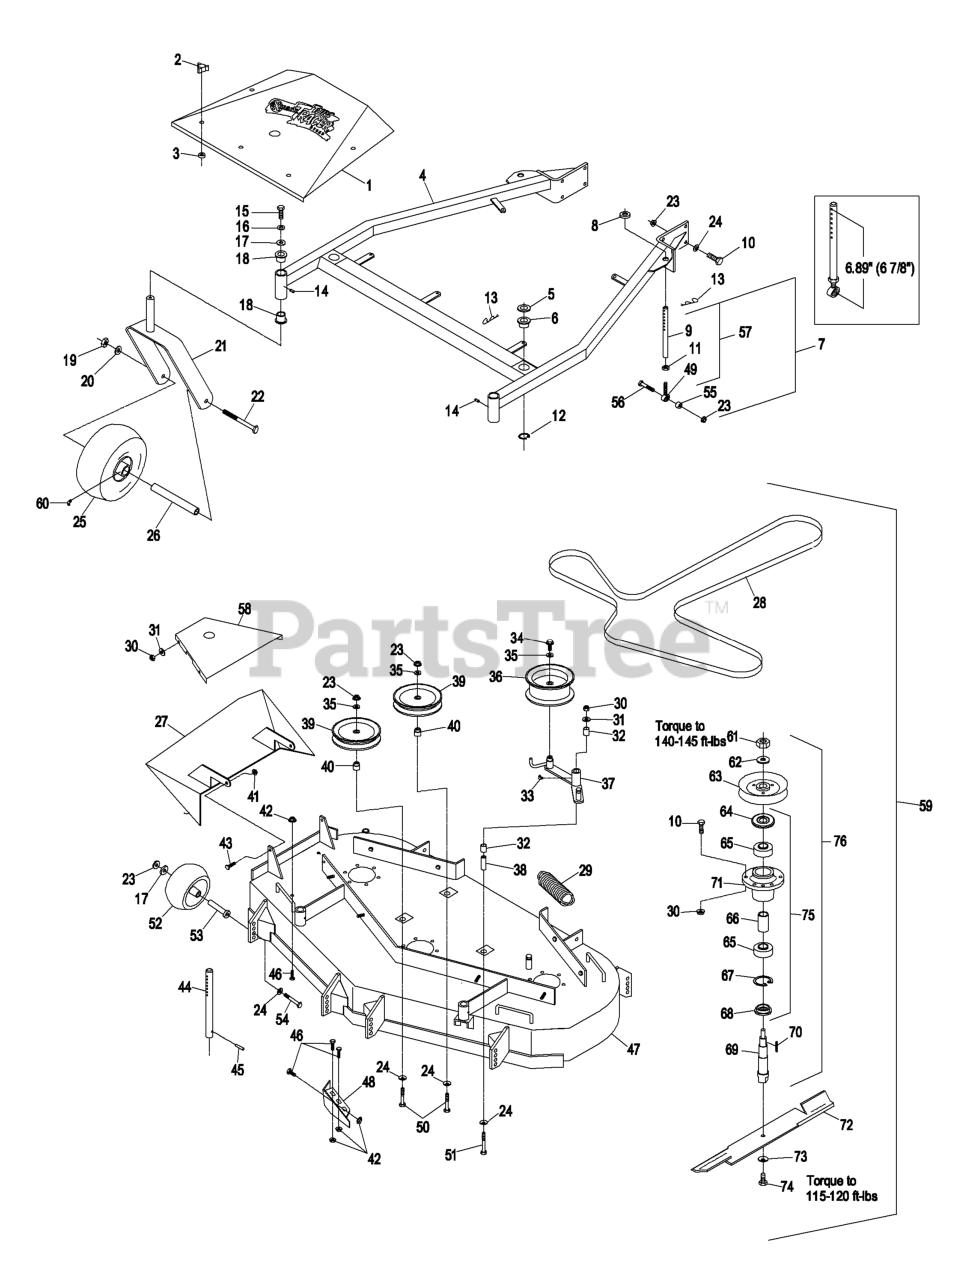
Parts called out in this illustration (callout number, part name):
2	KNOB-3 PRONG
4	SUPPORT,DECK W/BUSHINGS
5	SPACER-DECK SUPPORT
6	BUSHING-DECK
9	LINK,SUPPORT
10	SCREW-HH
11	NUT-HEX
12	RING-RETAINING
13	PIN,HAIR COTTER
14	FITTING-GREASE
15	SCREW-HH
16	WASHER-LOCK
18	BEARING-FLANGED
19	NUT-HH
20	WASHER-LOCK
22	SCREW-HH
23	NUT-HHF, WHIZ
24	WASHER-BELLEVILLE
26	SPACER FRONT CASTER
27	WLD,CHUTE DISCHARGE
28	BELT,DECK DRIVE
30	NUT-LOCK, NI
31	WASHER-FLAT
32	SLEEVE-BEARING
33	FITTING-GREASE, 90 DEG
34	SCREW-HHF
35	WASHER-FLAT
38	BUSHING-PIVOT, IDLER
39	PULLEY-IDLER
40	BUSHING-IDLER
41	NUT-LOCK, NI
43	SCREW-HH
44	ROD,DECK SUPPORT
46	SCREW-HH
47	ASM,DECK W/DECALS TTHP52
48	WLD,BAFFLE DISCHARGE
49	BALLJOINT
50	SCREW-HH
51	SCREW-HH
52	ROLLER-SCALP, ANTI
53	BUSHING-ROLLER
54	SCREW-HH
56	SCREW-HH
58	SHIELD,SIDE BELT 52
59	Assembly, Cutting Deck Complete
60	FITTING-GREASE
63	SHEAVE,W/HUB 5.72
64	GUARD-BEARING, TOP
65	BEARING-JACKSHAFT
66	SPACER-BEARING
67	RING-SNAP
68	SPACER-GUARD, BOTTOM
69	SPINDLE,SHAFT
70	KEY-RECTANGLE
73	WASHER-SPRING
74	SCREW-CAP
77	KIT, SP CASTER WHEEL REPL
